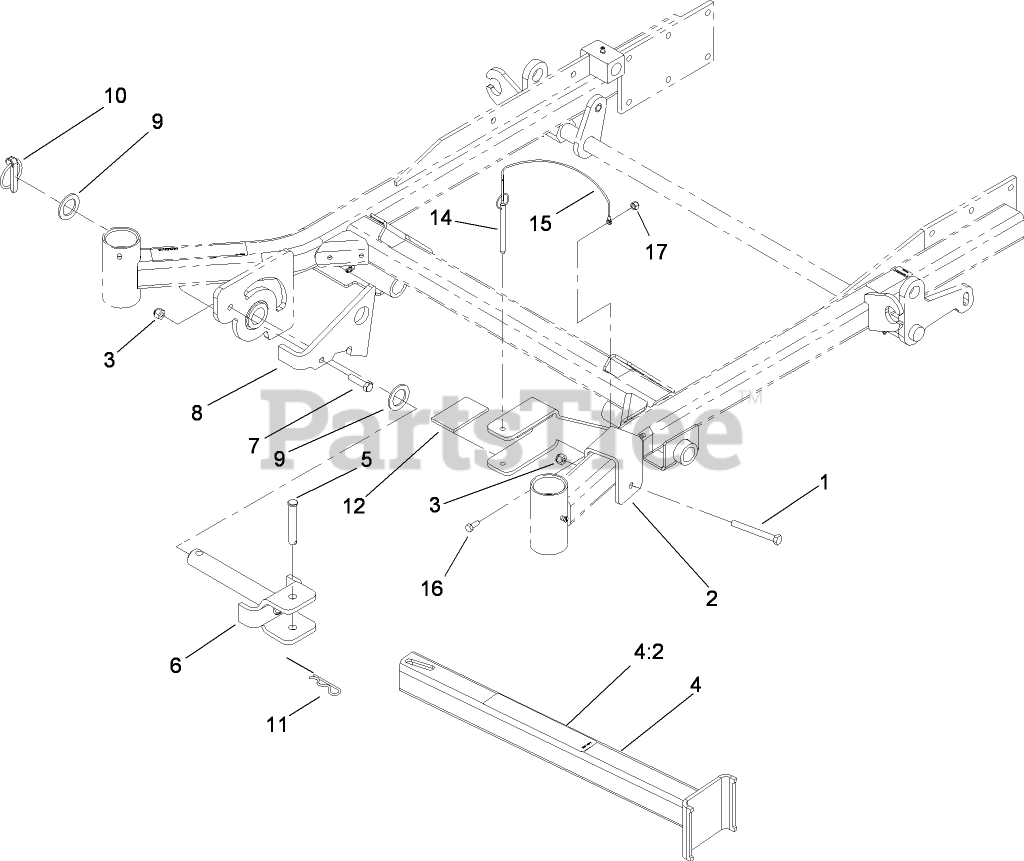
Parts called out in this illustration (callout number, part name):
1	SCREW-HH
2	BRACKET-CRADLE
3	NUT-LOCK, NI
4	Leg ASM
4:2	DECAL-Z STAND
5	PIN-CLEVIS
6	PIN-PIVOT
7	SCREW-HH
8	BRACKET-LATCH
9	WASHER-THRUST
10	PIN-LYNCH
11	PIN-HAIR
12	Cushion-Rubber
14	PIN-HITCH, COTTERLESS
15	LANYARD-NYLON
16	SCREW-HH
17	NUT-LOCK, NI
